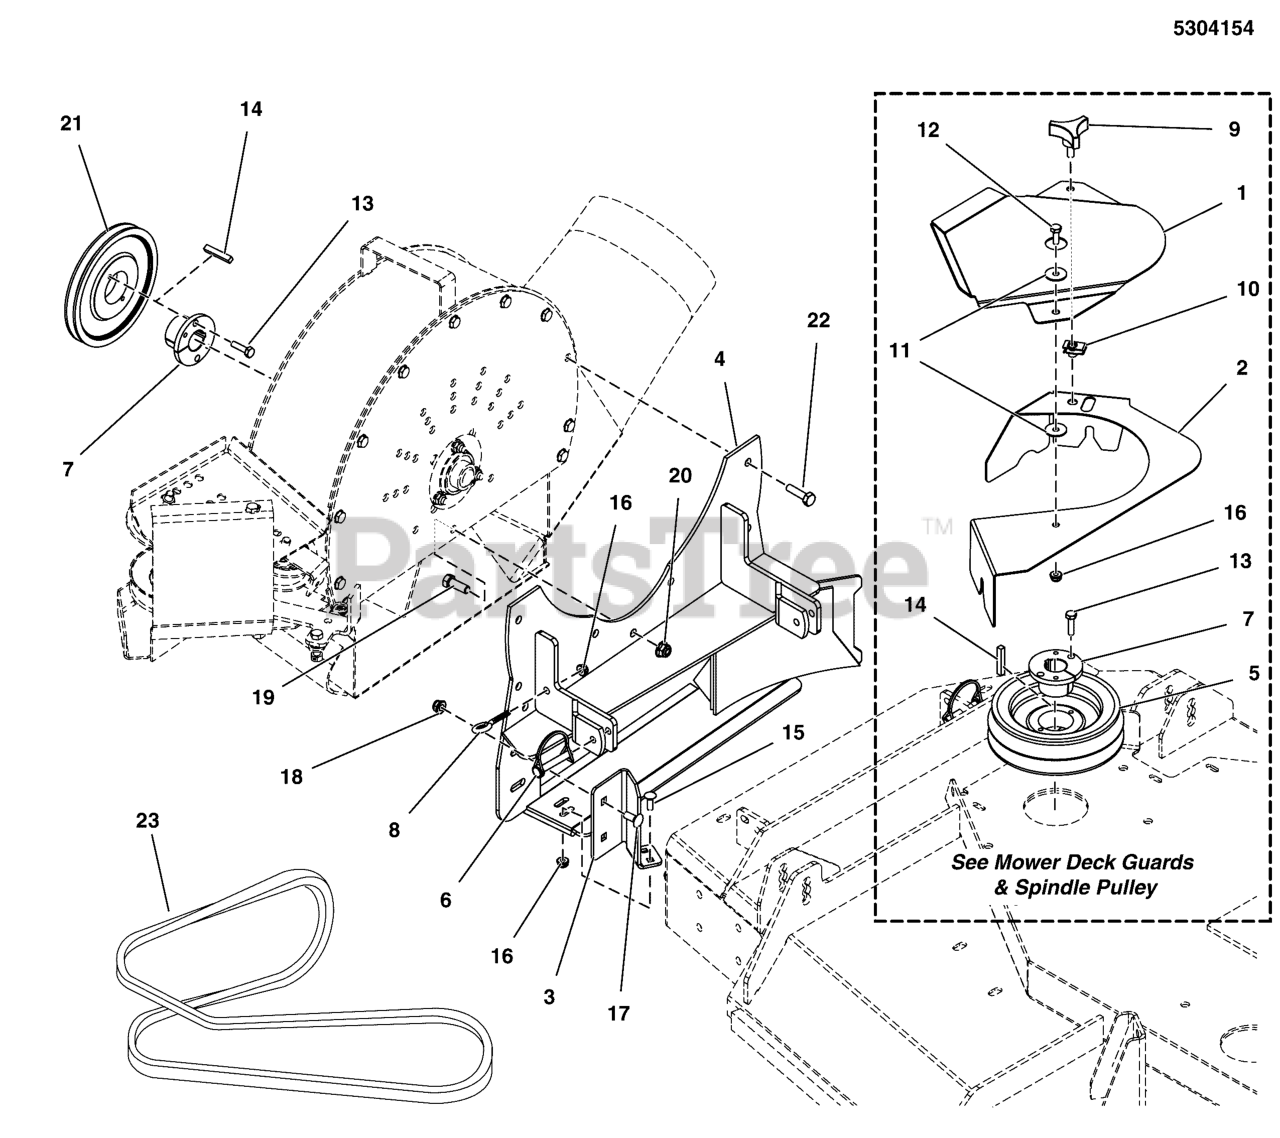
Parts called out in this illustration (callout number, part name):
1	SEE MOWER DECK GUARDS & SPINDLE PULLEY
2	SEE MOWER DECK GUARDS & SPINDLE PULLEY
3	BRACKET, DEFLECTOR PLATE, 61" iCD - BLK
4	WELD, ADAPTER, 61ICD, FVAC - BLK
5	SEE MOWER DECK GUARDS & SPINDLE PULLEY
6	SNAPPERPIN, 5/16 X 2
7	BUSHING, TAPERED HUB
8	EYE BOLT, 1/4-20 X 2.5, 1THRD, .5EYE,CZ
9	KNOB, PLASTIC, 5/16-18 X 3/4
10	BODY CLIP, 5/16-18-7GA MATERIAL
11	WASHER, 1/4 FENDER
12	BOLT, 1/4-20 X 3/4 GD5 CZ
13	BOLT, 1/4-20 X 1" GD5 CZ
14	KEY 1/4 SQ X 1 1/2 LONG
15	BOLT-RD HD SH SQ NK 1/4-20X0. 625 G5 BLK
16	NUT, 1/4-20 HEX NYLOCK FLANGE
17	BOLT, 5/16-18 X 3/4, CARRIAGE
18	NUT, 5/16-18 HEX NYLOCK FLANGE
19	BOLT, 3/8-16 X 1" GD5 CZ
20	NUT, 3/8-16 HEX NYLOCK FLANGE
21	PULLEY, SPLIT STEEL, 6.432"OB, HQ BORE
22	BOLT, 5/16-18 X 1, SELF-TAPPING
23	BELT, A-SEC, 102.9"EL, ARAMID, WRPD
